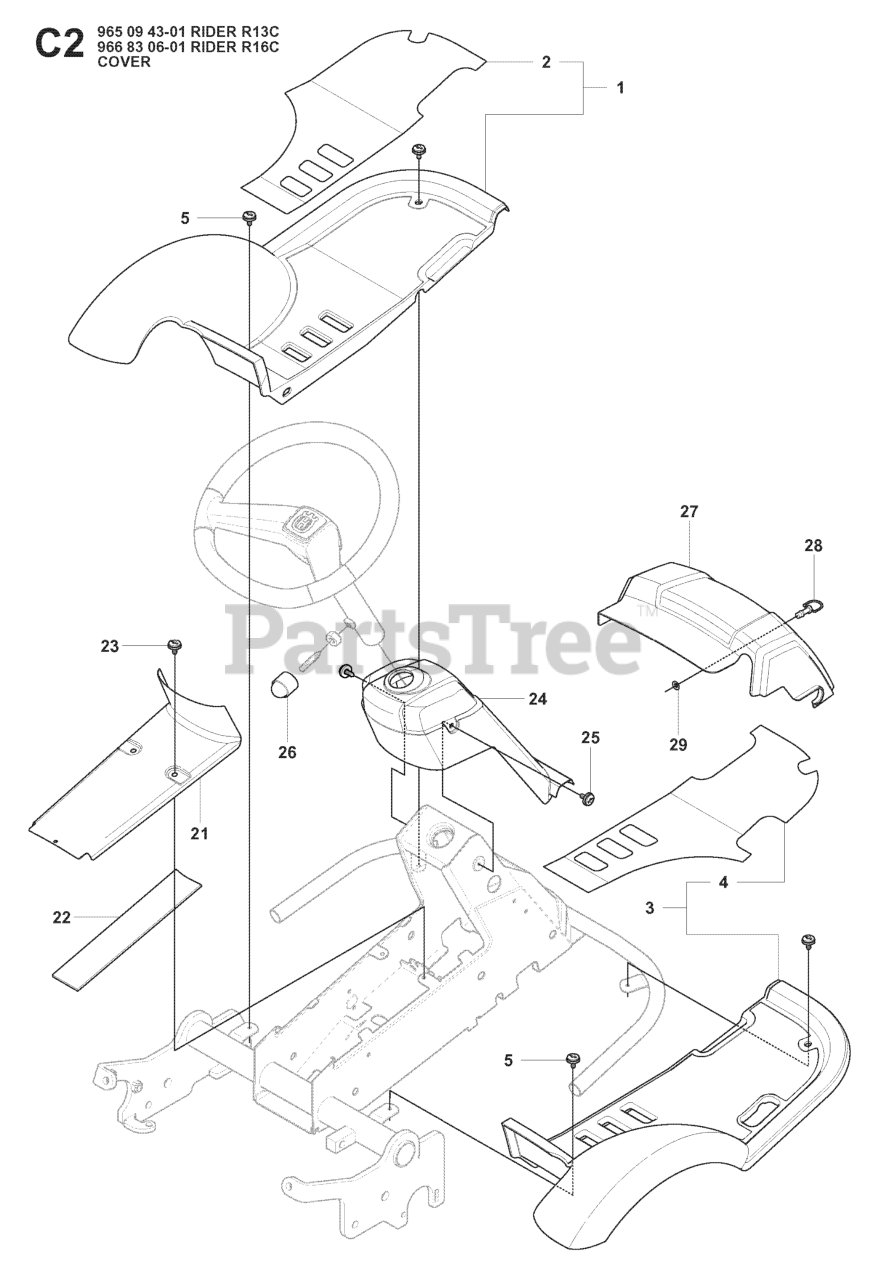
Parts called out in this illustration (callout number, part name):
1	FOOT PLATE
3	FOOT PLATE
26	PROTECTIVE COVER
28	BOLT
